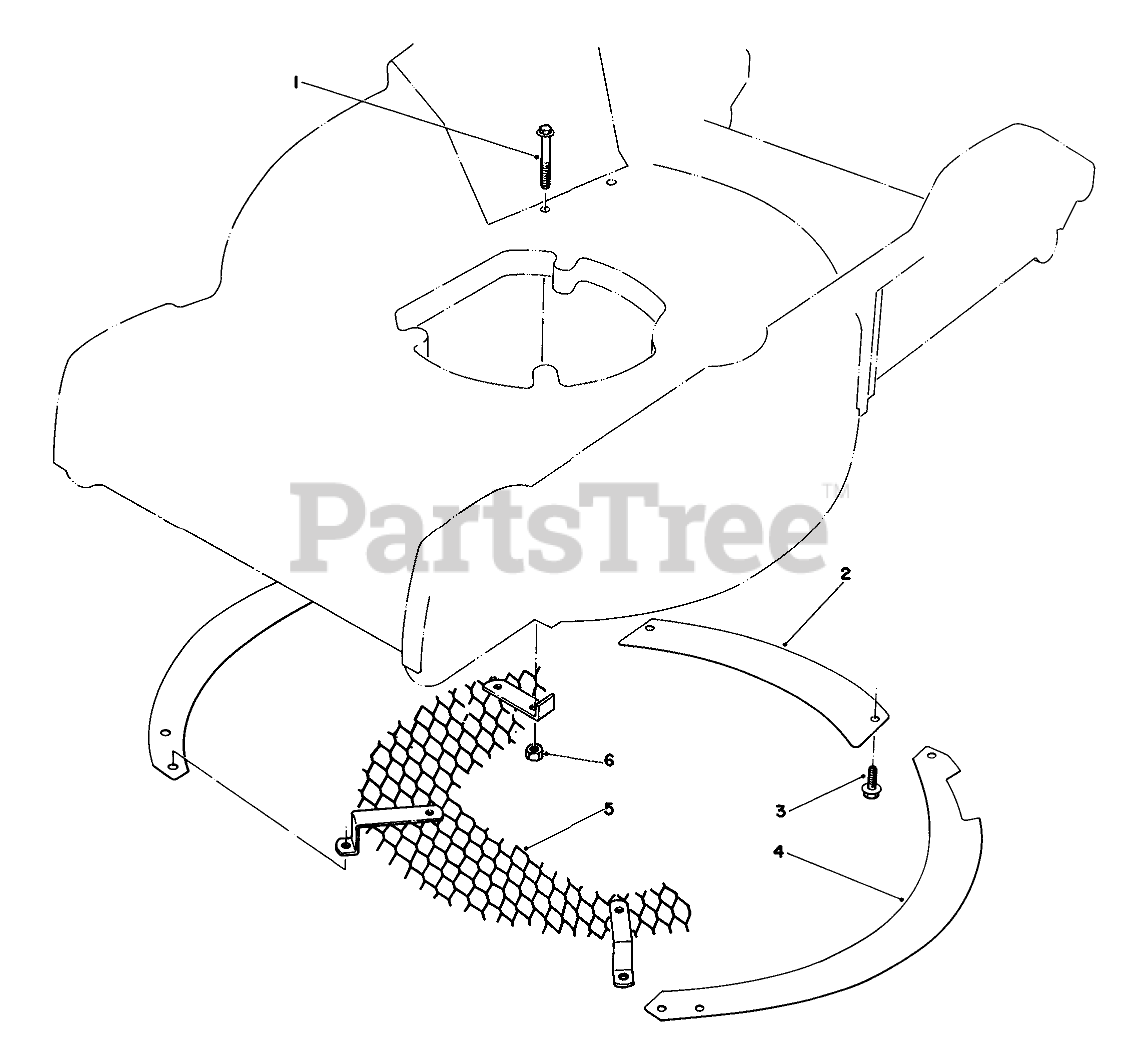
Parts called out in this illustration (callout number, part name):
1	Screw
2	Rear Baffle
3	SCREW
4	Outer Baffle
5	Screen
6	NUT-LOCK
